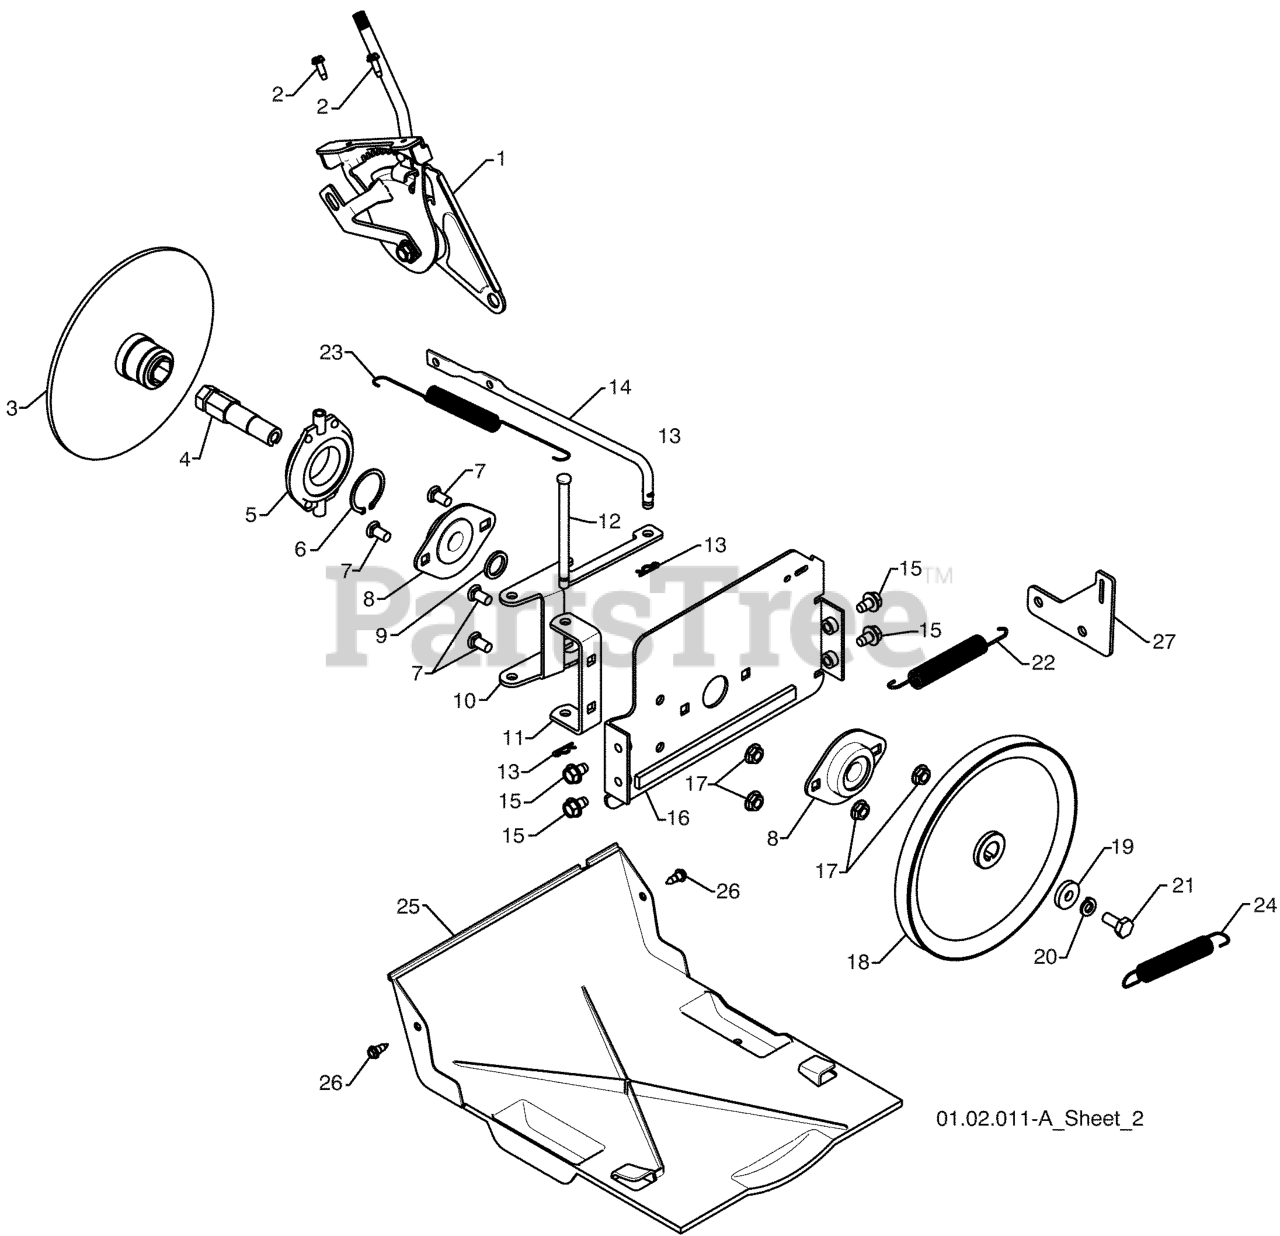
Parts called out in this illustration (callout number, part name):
1	HEAD ASSY SPEED
2	SCREW #10-24 X 5/8
3	DRIVE PLATE WELDMENT
4	SHAFT.HEX.SHORT
5	TRUNNION BEARING ASSY
6	RETAINING RING (2 2)(3 2)
7	BOLT
8	BEARING FLANGE
9	SPACER, BEARING
10	LEVER.SHIFTER.PLATE.BLACK
11	BRACKET, SHIFTER SUPPORT
12	PIN, PIVOT LEVER
13	RETAINER CLIP PM
14	ROD.CLUTCH.YELLOW.ZINC(VT)
15	BOLT 5/16-18 X .500
16	PLATE.DRIVE.MOUNTING.BLACK
17	NUT.FLANGE.5/16
18	PULLEY.TRACTION.7.75
19	WASHER, FLAT
20	WASHER.LOCK.HVY.HLCL.SPR.5/16
21	SCREW 5/16-18 X .750
22	RP SPRING, TRACTION IDLER
23	SPRING.RETURN
24	SPRING, BRAKE
25	PAN.BOTTOM.PLASTIC
26	SCREW, HEX HEAD, TAPPING
27	BRACKET.TRACTION.SPRING.
